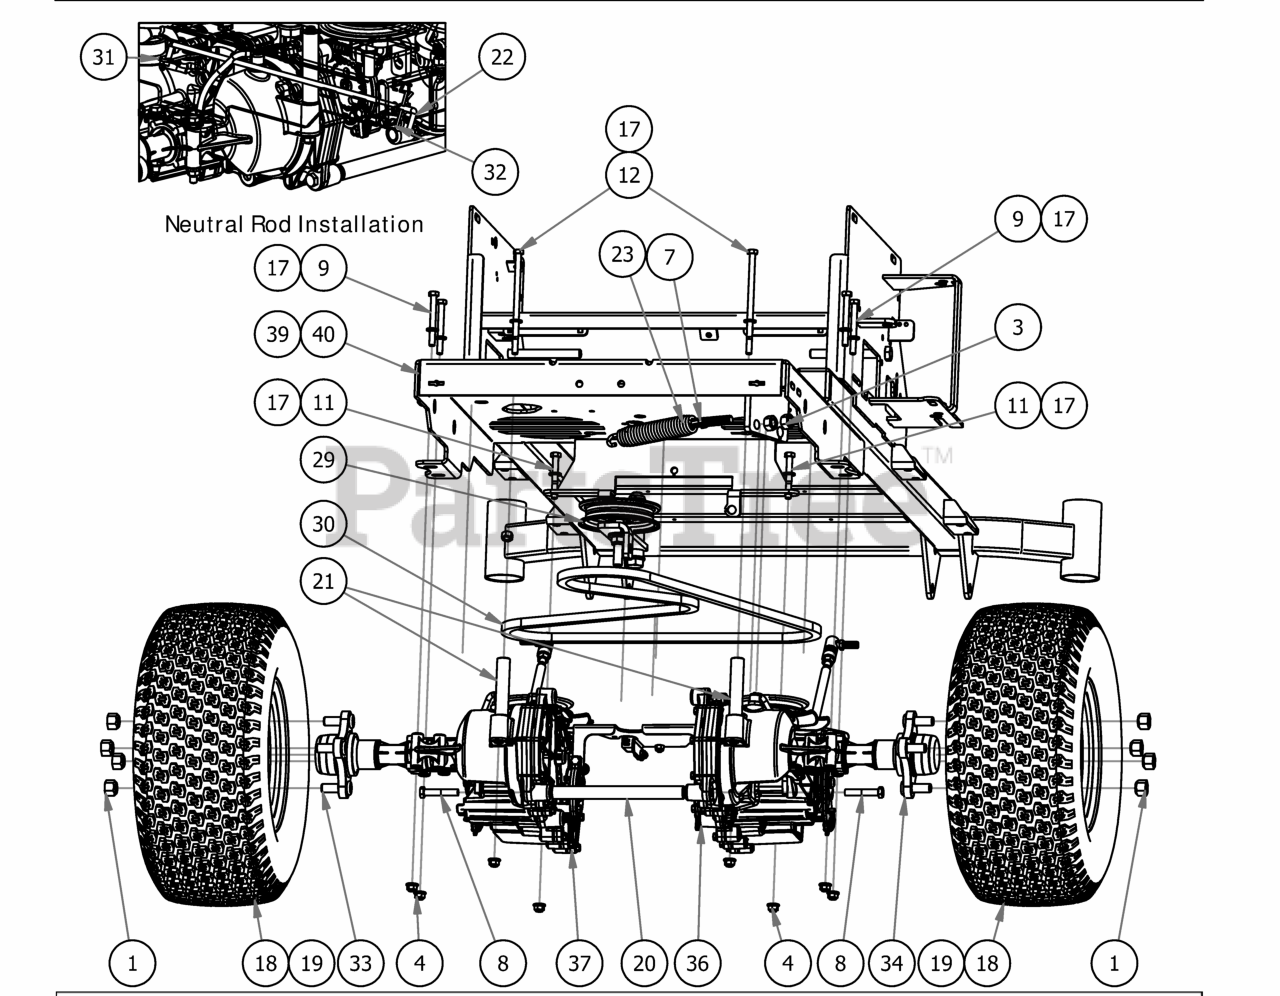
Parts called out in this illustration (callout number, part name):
1	Acorn Lug Nut
3	1/2" Hex Nut
4	5/16" Nylon Flange Nut
7	All Thread-Pump Idler Tensioner
8	3/8"-16 x 2" Gr 5 Hex Bolt
9	5/16" x 3" Hex Bolt
11	5/16" x 2 1/2" Bolt
12	5/16" x 6" Bolt
17	5/16" Flat Washer
18	Wheel & Tire Assembly, 18x8.50-8, 42" MZ
19	Wheel & Tire assembly, 18x9.50-8, 48"-54" MZ
20	2017 Transaxle Spacer-MZ
21	2017 Transaxle Spacer
22	Neutral Rod
23	Deck Idler Spring
29	ZT Pump Idler
32	Neutral Rod Clip
33	Transaxle Wheel Studs
34	MZ 4 Bolt Hub Kit
36	2017 MZ Right Transaxle
37	2017 MZ Left Transaxle
39	2017 MZ/ZT 54"-60" Frame
40	2017 MZ/ZT 42"-48" Frame
